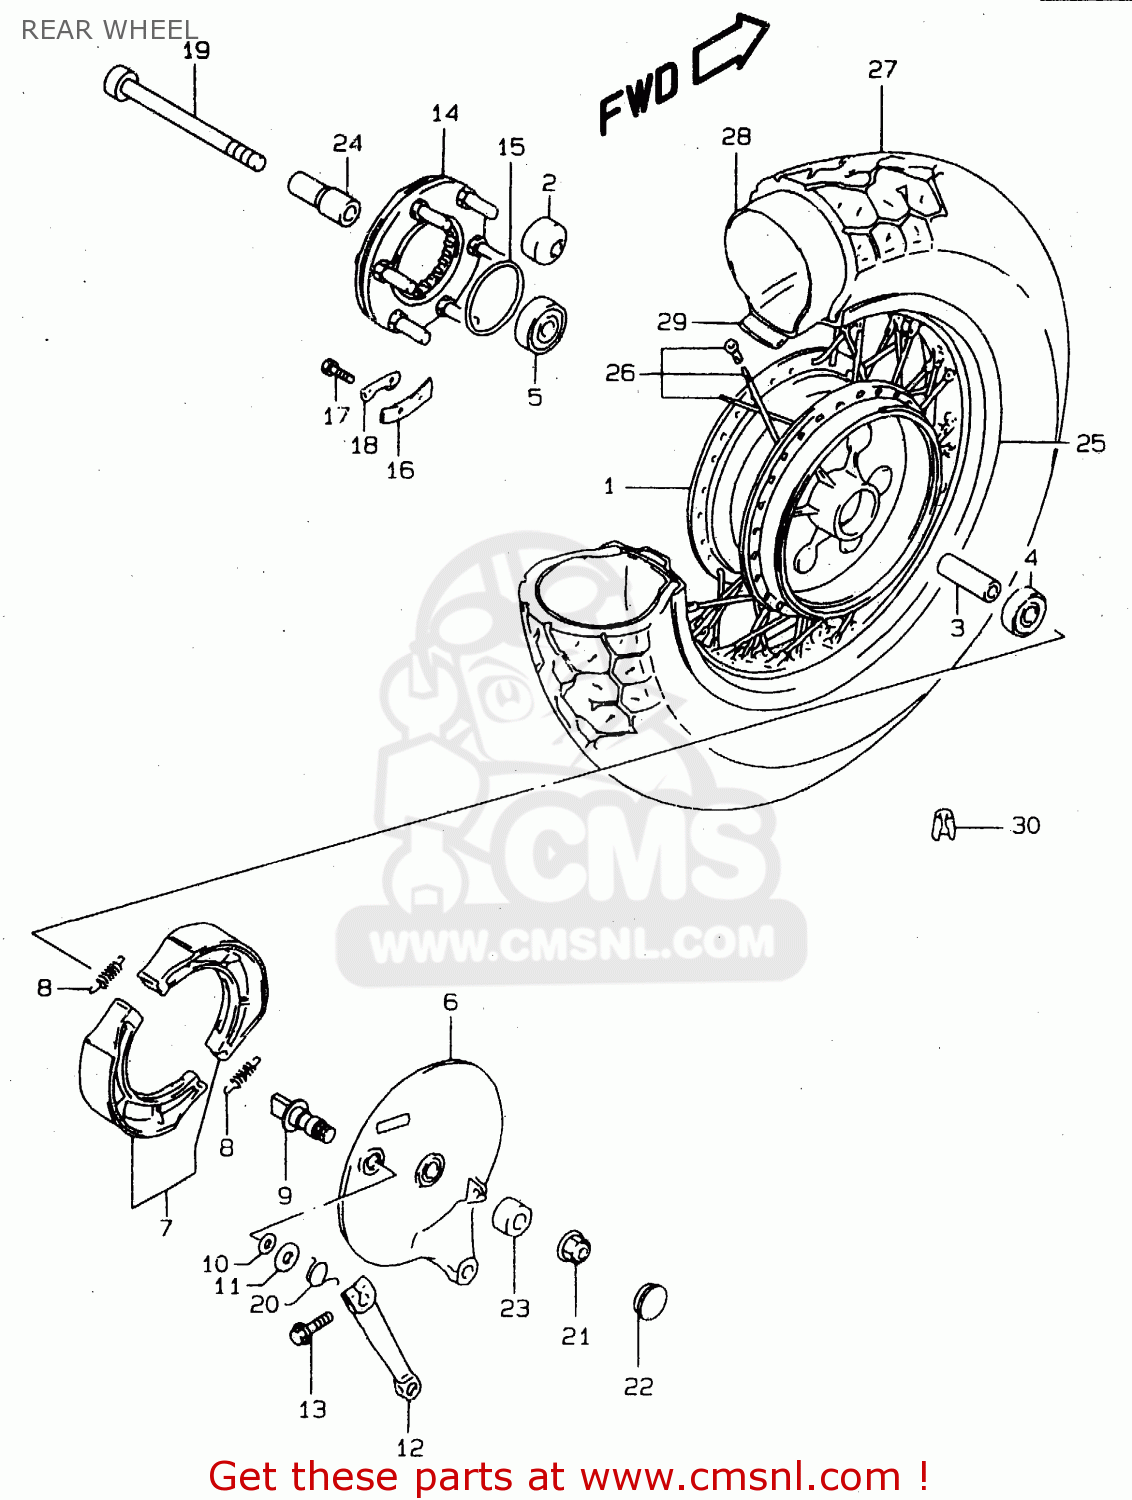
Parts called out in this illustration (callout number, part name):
1	HUB SET,RR
2	BUSH
3	SPACER(17.5X25X80)
4	BEARING
5	BEARING
6	PANEL,RR BRAKE ANCHOR
7	SHOE SET,BRAKE (NAS)
8	SPRING,BRAKE SHOE
9	CAM,RR BRAKE
10	O RING(D:2.4,ID:14.8)
11	WASHER(15.5X24X1.6)
12	LEVER,RR BRAKE CAM
13	BOLT
14	JOINT ASSY,RR HUB DRIVEN
15	O RING(D:2.1,ID:65)
16	WASHER,THRUST(T:1.6)
17	BOLT(6X16)
18	WASHER
19	AXLE,RR
20	SPRING
21	NUT
22	CAP,RR AXLE,R
23	SPACER,RR AXLE,L
24	SPACER,RR AXLE,L
25	RIM,RR WHEEL MT(3.00X15 M/C)
26	SPOKE ASSY,RR WHEEL
27	TIRE,REAR 140/90-15M/C
28	TUBE ASSEMBLY,WHEEL,INNER
29	PROTECTOR,WHL INR TUBE
30	BALANCER,WHEEL
